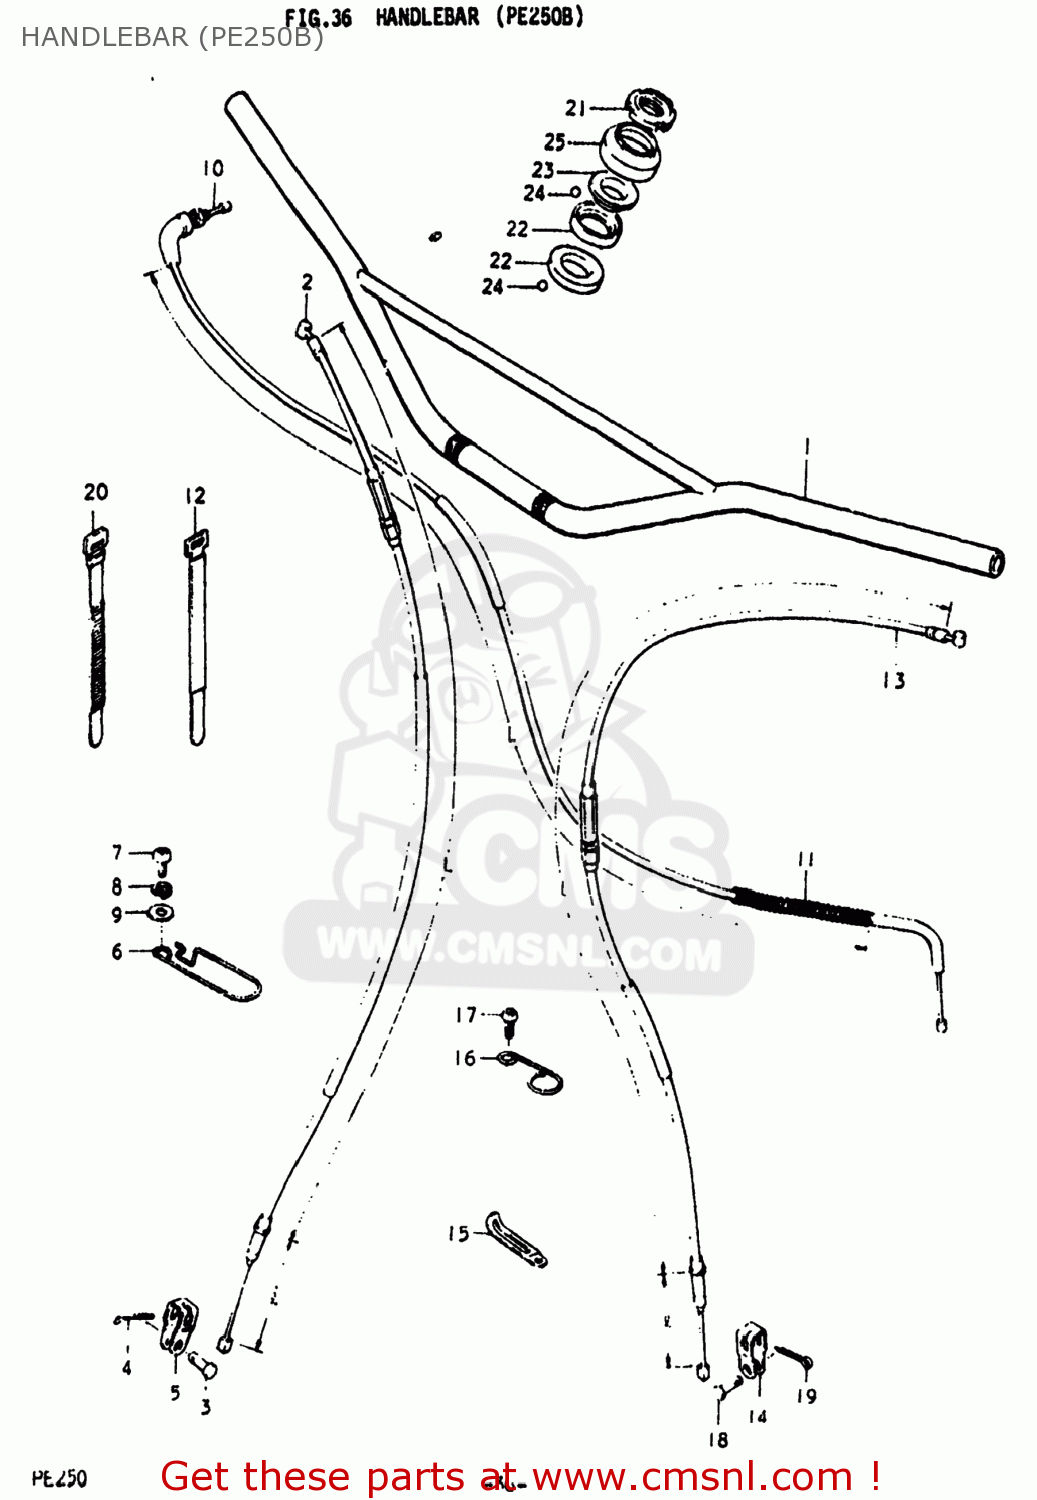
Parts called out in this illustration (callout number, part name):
1	HANDLEBAR
2	CABLE ASSEMBLY,FRONT BRAKE
3	PIN(L:13.5)
4	PIN
5	BRAKE CABLE HOOK
6	GUIDE,CABLE
7	SCREW 6X12
8	LOCK WASHER
9	WASHER
10	CABLE ASSEMBLY,THROTTLE
11	PROTECTOR,CABLE
12	CLAMP
13	CABLE ASSEMBLY,CLUTCH
14	HOOK,CLUTCH CABLE
15	CLAMP
16	CLAMP
17	SCREW 6X12
18	PIN(L:13)
19	PIN
20	CLAMP(L:120)
21	NUT,STEERING STEM(25X44X10)
22	LACE,STEERING INNER LWR
23	LACE,STEERING OUTER UPR
24	BALL
25	DUST SEAL,STEERING UPR
